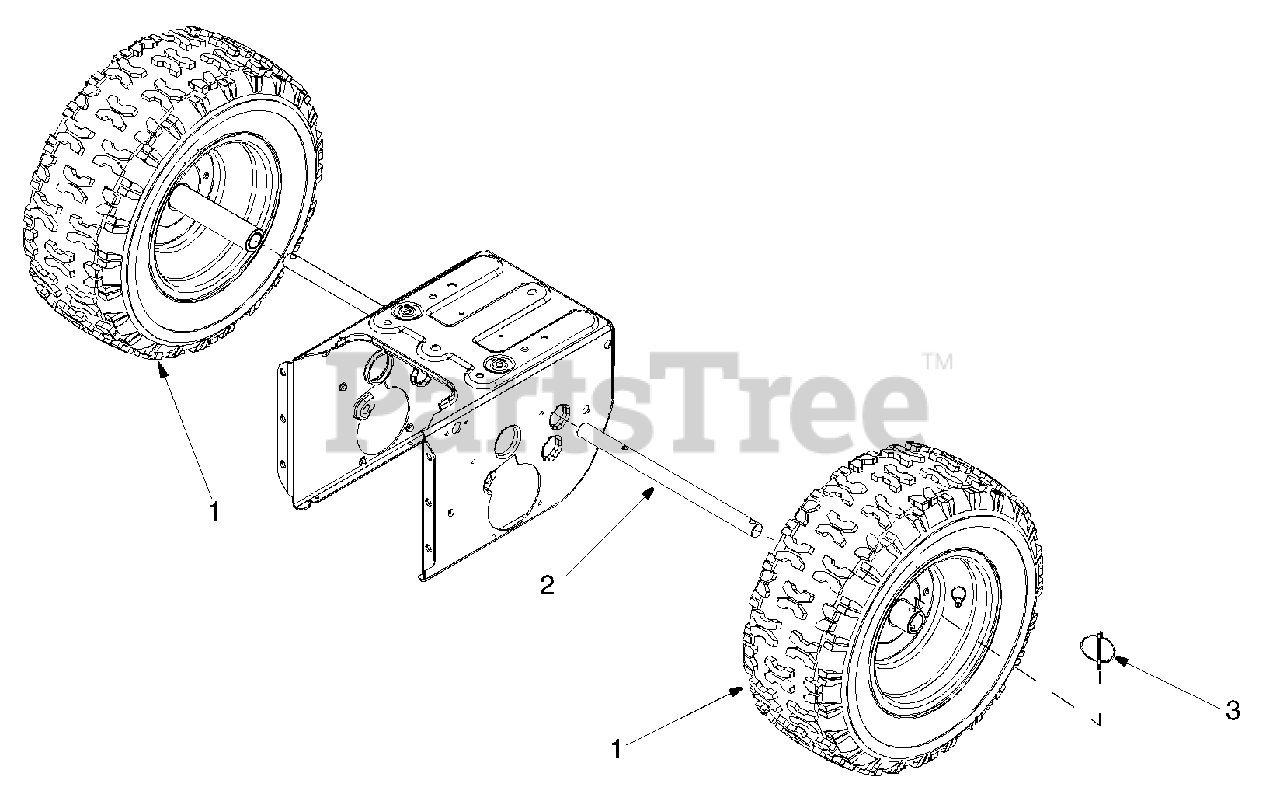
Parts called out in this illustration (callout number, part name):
1	Wheel Assembly: 16.5 x 4.8 Steerable
2	Axle: 0.75" dia. x 12.201" Lg.
3	Klick Pin
